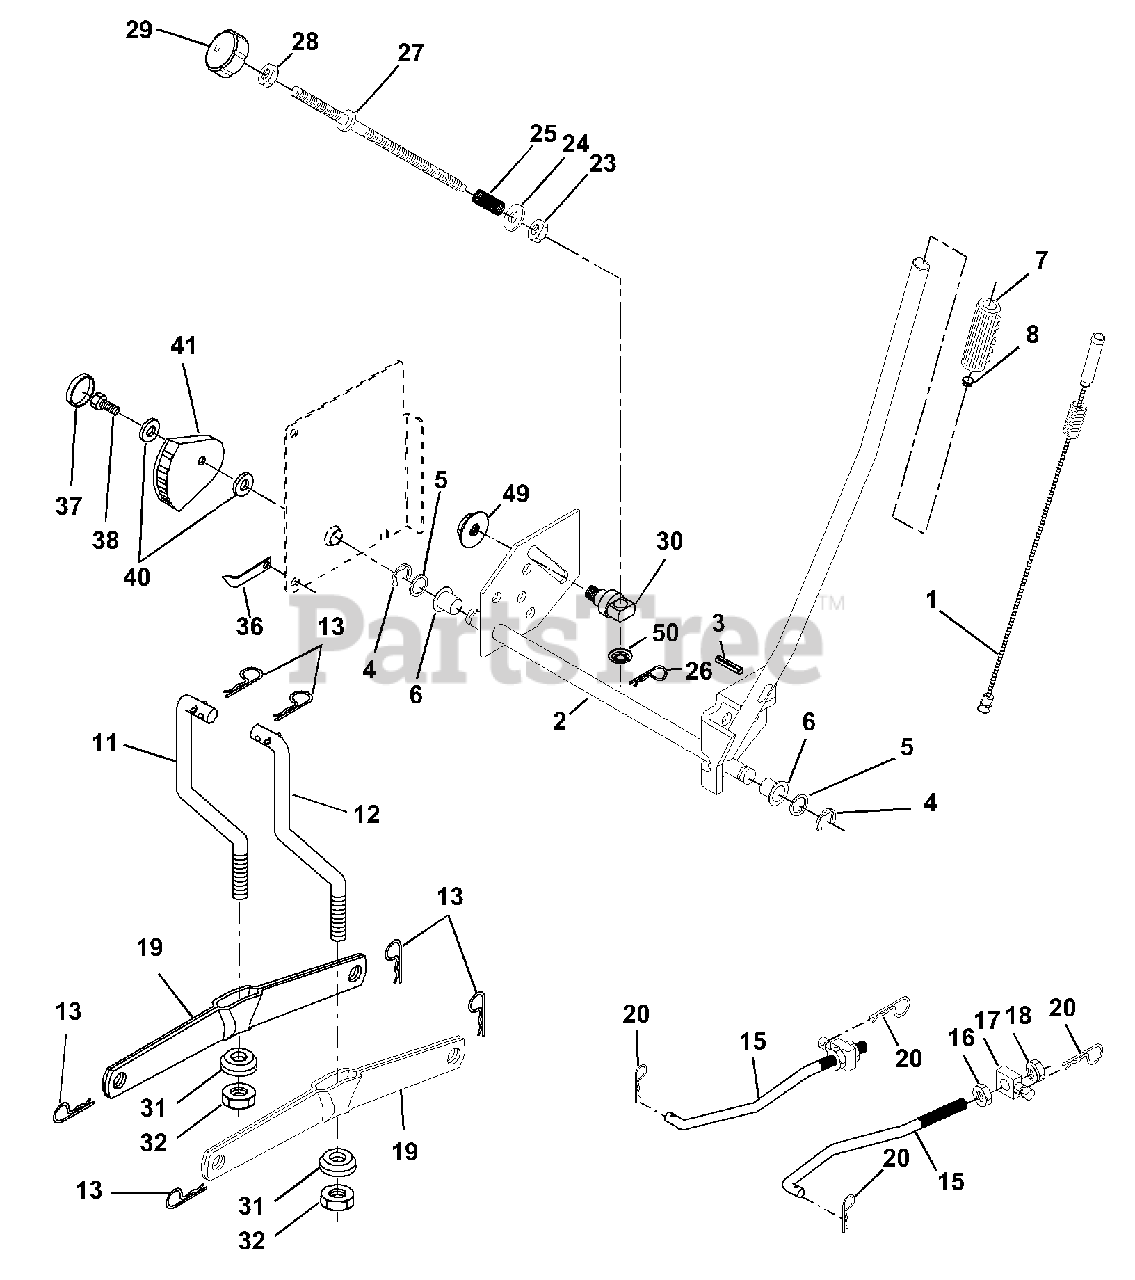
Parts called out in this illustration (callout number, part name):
1	Wire Asm Inner/Spring W/Plunger LT
2	Shaft Asm Lift RH w/Inf
3	Pin Groove 1 500 Zinc
4	E Ring #5133-62
5	Washer 21/32 X 1 X 21 Ga
6	Bearing Nylon Blk 629 Id
7	Grip Handle Fluted Blk
8	Button Plunger Black
11	Link Lift LH
12	Link Lift RH
13	Retainer Spring
15	Link Front
16	Nut Jam Hex 1/2-13 Unc
18	Nut Lock w/Wsh 1/2-13unc
19	Arm Suspension Rear
20	Retainer Spring
23	Nut Special
24	Washer 13/32 X 5/8 X 16 Ga
25	Spring 2-1/8"
26	Retainer Clip
27	Rod Adj Lift Zinc 7.49 Wrk Lg
28	Nut Hex Jam 3/8-16 Unc
29	Knob Inf 3/8-16 Unc Blk W/sym
30	Trunnion Infin Height
31	Bearing PVT Lift
32	Nut Crownlock 3/8-24
36	Indicator Height STLT
37	Plug Hole Blk 1.485/1.515 Dia.
38	Screw 5/16-18 x 1
40	Washer 11/32 x 1-1/2 10 Ga.
41	Scale Ind. Height Blk.
49	Nut Hex Flange Lock
50	Nut, Push Phos & Oil
